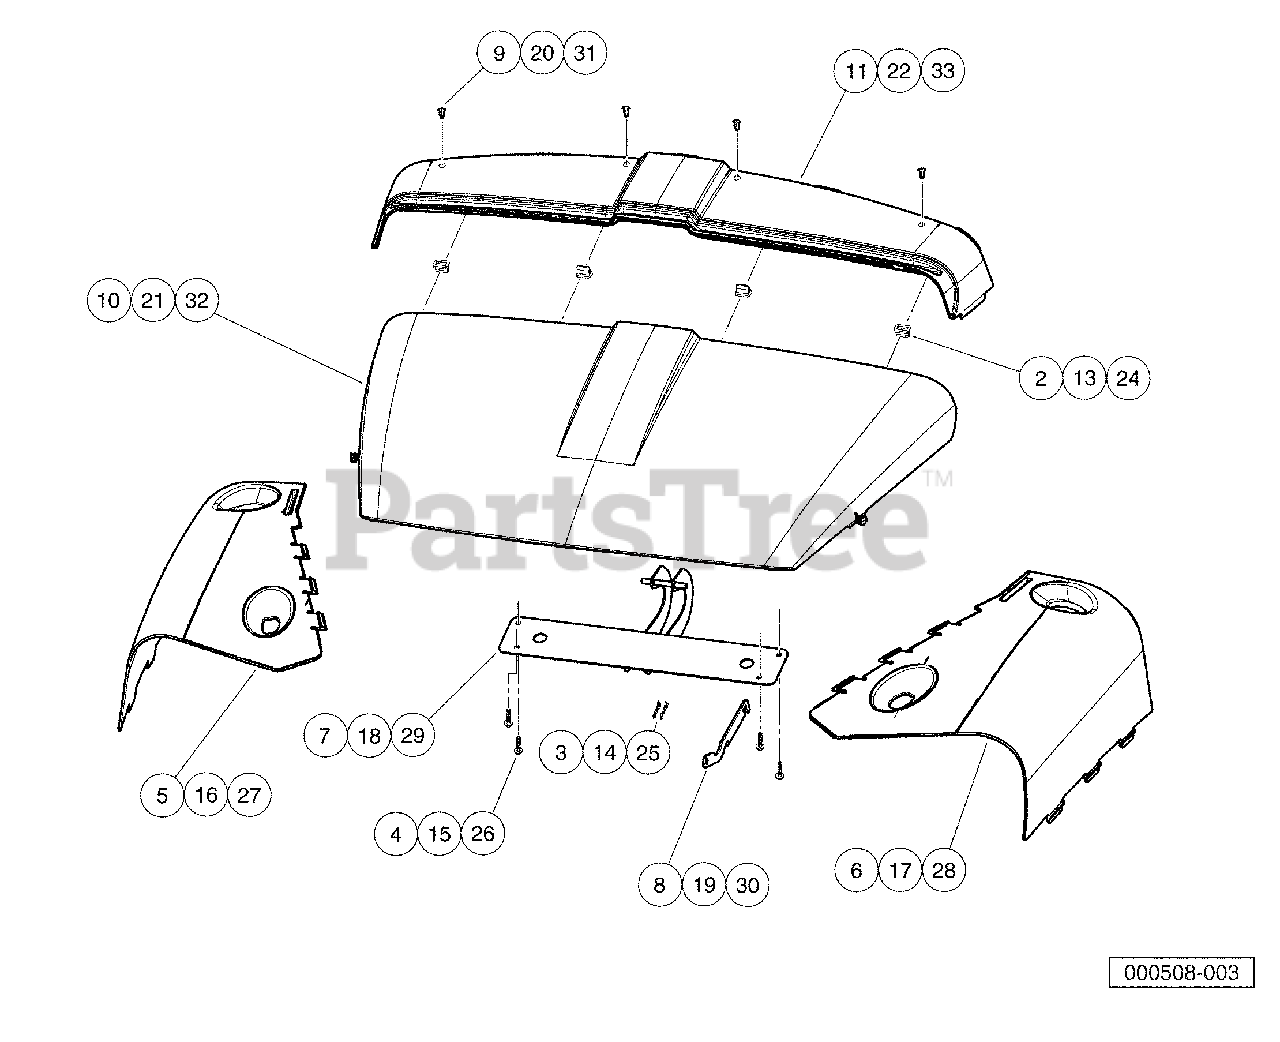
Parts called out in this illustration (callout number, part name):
1	Option, Color, Huv, Camo
2	Clip-body-trim
3	Pin, Bow Tie Locking - .072
4	Screw,m6,torx,interlock,thread.
5	Panel, Cowl, Passenger-Side, Real Tree Camo
6	Panel, Cowl, Driver-Side, Real Tree Camo
7	Weldment, Hinge, Hood
8	Prop, Hood
9	Rivet, Removable, Tuflok 1/4"
10	Hood, Design B, Moff
11	Panel, Cowl, Upper, B,moff
12	Option, Color, HUV, Orange
13	Clip-body-trim
14	Pin, Bow Tie Locking - .072
15	Screw,m6,torx,interlock,thread.
16	Panel, Cowl, Ps, Orange
17	Panel, Cowl, Drv, Orange
18	Weldment, Hinge, Hood
19	Prop, Hood
20	Rivet, Removable, Tuflok 1/4"
21	Hood, Design B, Orange
22	Panel, Cowl, Upper, B, Orange
23	Option, Color, Huv, Olive Grn
24	Clip-body-trim
25	Pin, Bow Tie Locking - .072
26	Screw,m6,torx,interlock,thread.
27	Panel, Cowl, Ps, Olive Green
28	Panel, Cowl, Drv, Olive Green.
29	Weldment, Hinge, Hood
30	Prop, Hood
31	Rivet, Removable, Tuflok 1/4"
32	Hood, Design B, Olive Grn
33	Panel, Cowl, Upper, B, Olv Grn
